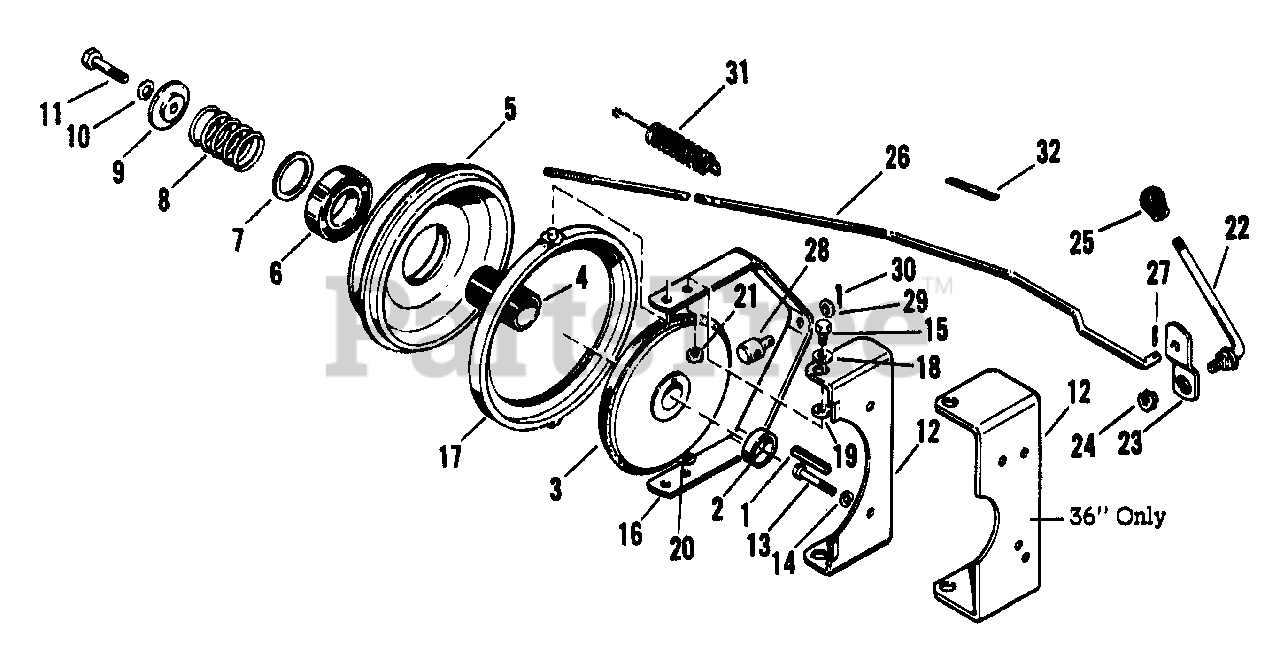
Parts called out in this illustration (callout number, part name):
1	KEY, Hi-Pro
3	Cluth Plate Assembly
6	Ball Bearing
9	Thrust Plate
10	Lock Washer, 3/8"
11	Hex Capscrew, 3/8"-24 x 1-3/4"
13	Hex Capscrew, 5/16"-18 x 1-3/4"
14	Lock Washer, 5/16"
15	Hex Capscrew, 5/16"-18 x 3/4"
16	Clutch Fork
17	Brake Support Assembly
20	Plain Washer, 1/4"
21	Hex Nut, Full, Lock, 5/16"-18
22	Clutch Control Handle
23	P.T.O. Arm
24	Hex Nut, Full, Lock, 3/8"-16
25	Knob
26	Clutch Rod
27	Cotter Pin, 3/32" x 1/2"
29	Plain Washer, 1/4"
30	Cotter Pin, 3/32" x 1/2"
